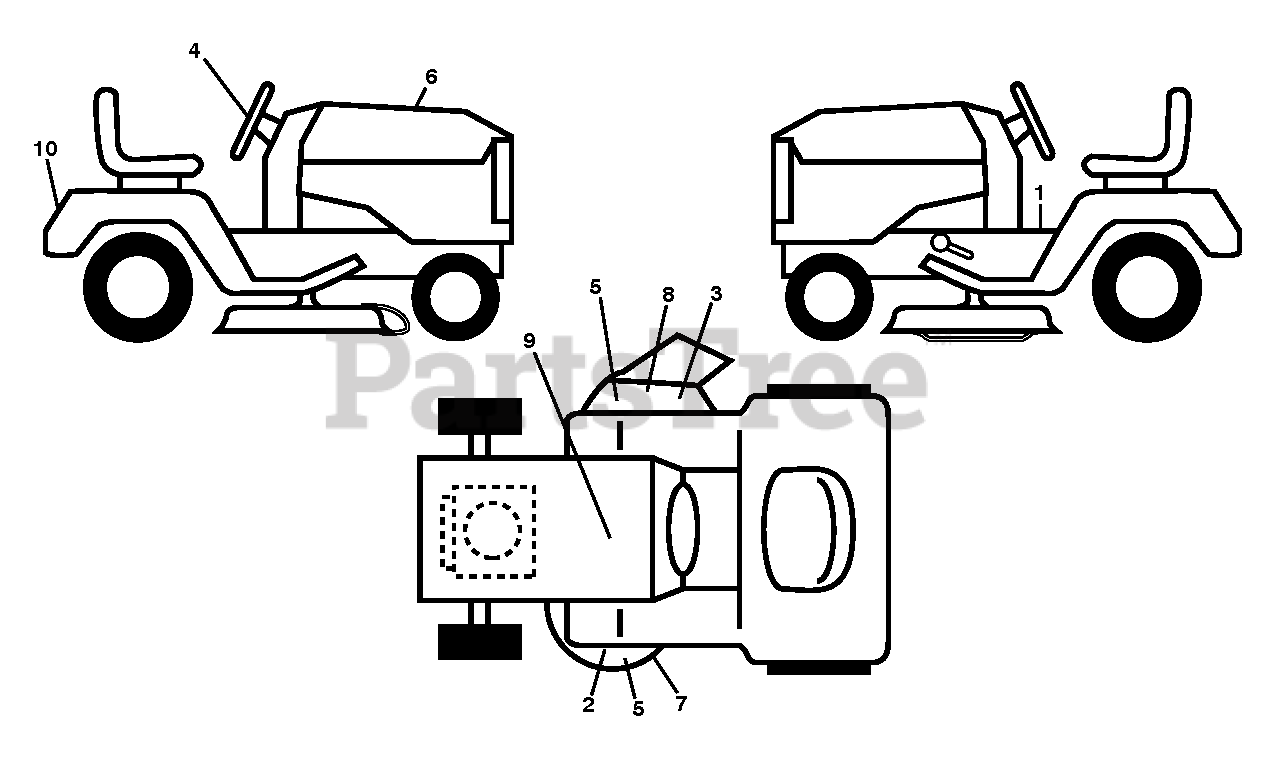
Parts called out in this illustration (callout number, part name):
1	Fender Warning Decal, English
3	Deflector Shield Warning Decal
5	No Step Decal
6	Decal, Replacement Kohler KT7 PRO TGB 52F G
7	Mower Schematic Decal, 48/54 Prem
8	DECAL, DECK DEFLECTOR, WARNING
9	DECAL BTRY SYMBOLS
